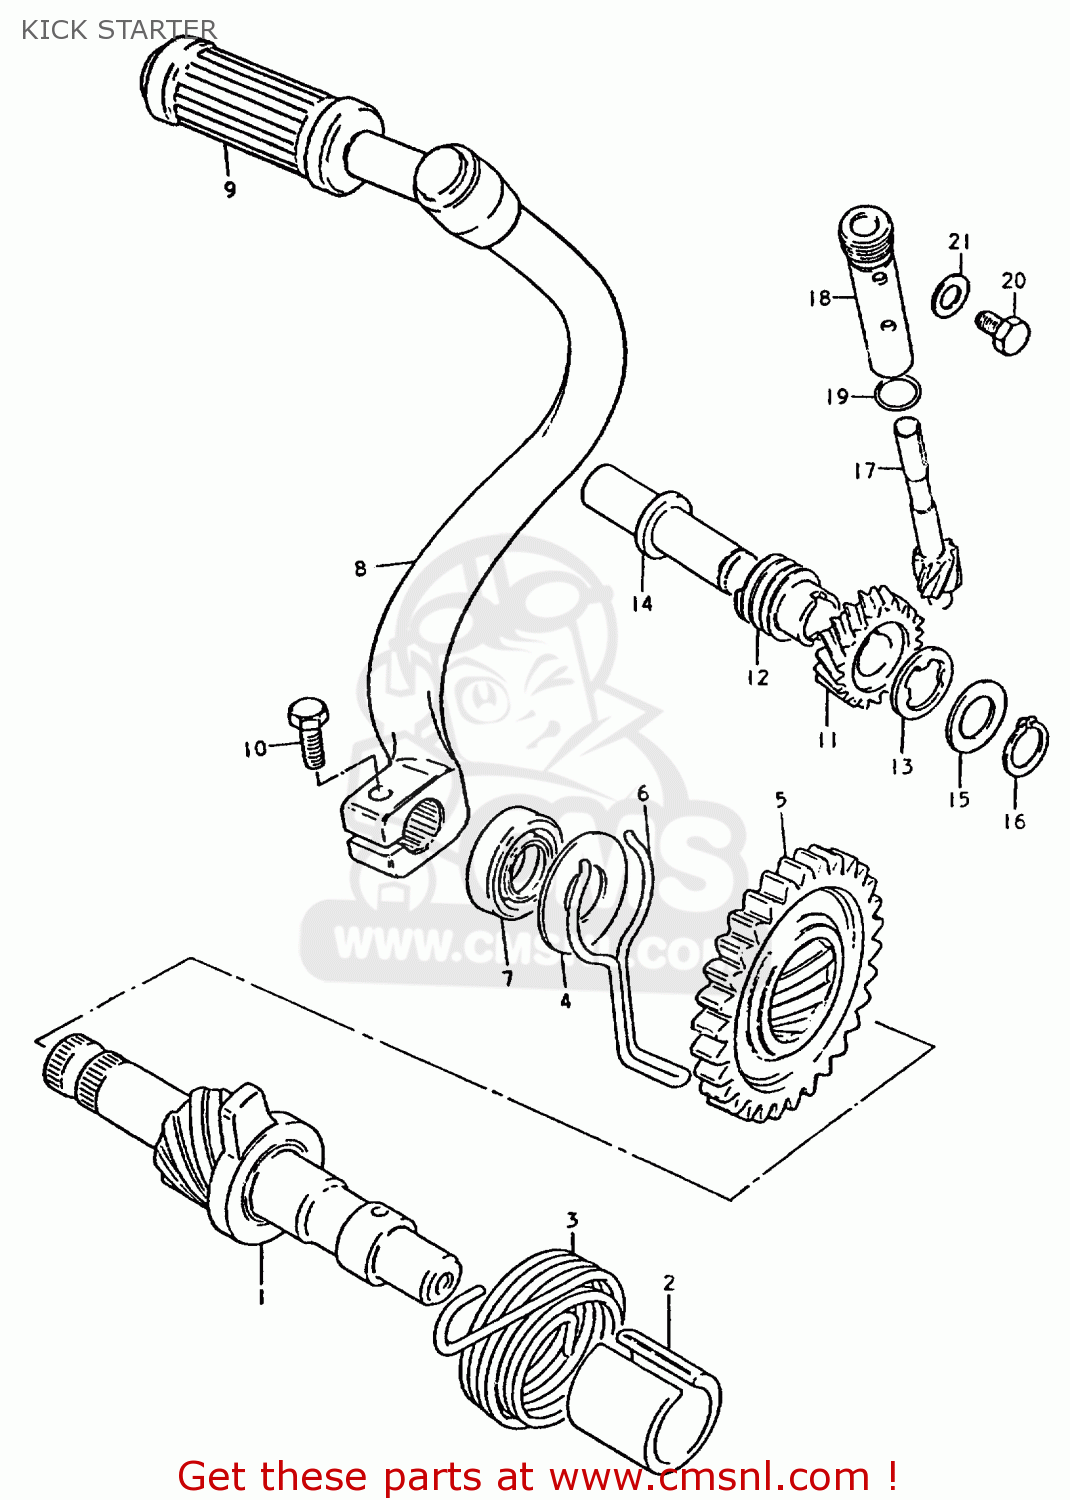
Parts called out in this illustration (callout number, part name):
1	SHAFT,KICK STARTER
2	GUIDE,KICK STARTER SFT SPRING
3	SPRING
4	WASHER
5	GEAR,KICK STARTER DRIVE(NT:30)
6	RETAINER,SNAP
7	SEAL,OIL(14X24X6)
8	LEVER ASSY, KICK STARTER
9	RUBBER,KICK STARTER PEDAL
10	BOLT
11	GEAR, TACHOMETER DRIVE NO.2
12	GEAR,TACH DRIVE NO.2(NT:3)
13	RETAINER,TACH DRIVEN GEAR NO1
14	SHAFT,TACHOMETER DRIVEN GEAR
15	WASHER,THRUST
16	CIRCLIP
17	GEAR,TACHOMETER DRIVEN(NT:12)
18	SLEEVE
19	O RING(D:1.3,ID:9.6)
20	BOLT
21	WASHER
